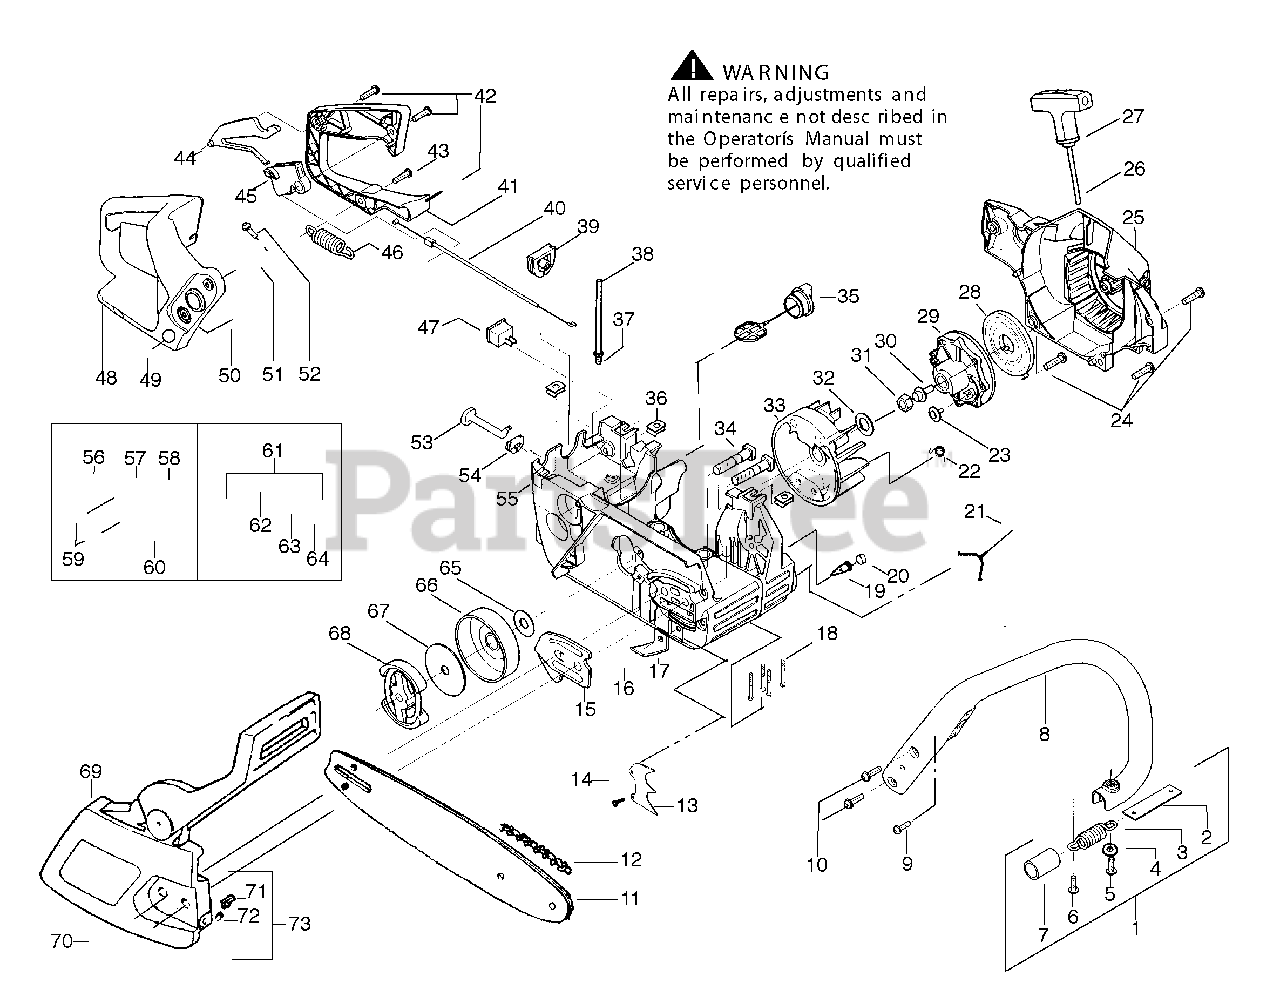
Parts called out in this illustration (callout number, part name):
1	ASSY-ISOLATOR
2	STRAP
3	SPRING
8	HANDLE
13	SPIKE 36/41
14	SCREW-10-16 X 1/2, TYPE 2
17	CHAIN CATCHER 36/41
19	VALVE-CHECK (DUCKBILL)
20	BRONZE PLUG
21	OIL TANK CAP
22	SPRING STR DOG
24	SCREW,STRTR CVR 36/41
27	HANDLE STARTER
29	STARTER PULLEY
31	NUT-FLYWHEEL
32	WASHER-FLYWHEEL
33	FLYWHEEL ASS'Y
35	TANK CAP
37	FUEL LINE FITTING
40	THROTTLE WIRE
42	SCREW,FRONT HBAR 36/41
43	SCREW-10-14 X 13/16 (PL
44	THROTTLE LOCK
45	THROTTLE TRIGGER
46	SPRING
50	SPRING
51	SPRING
57	WORM GEAR
62	PICK-UP OILER
63	FILTER
64	PLUG
65	DUST COVER 36/41
66	CLUTCH DRUM ASSY
67	FRICTION DISC,CLUTCH 36/41
68	CLUTCH ASSEMBLY
71	ADJUST PIN,BAR 36/41
